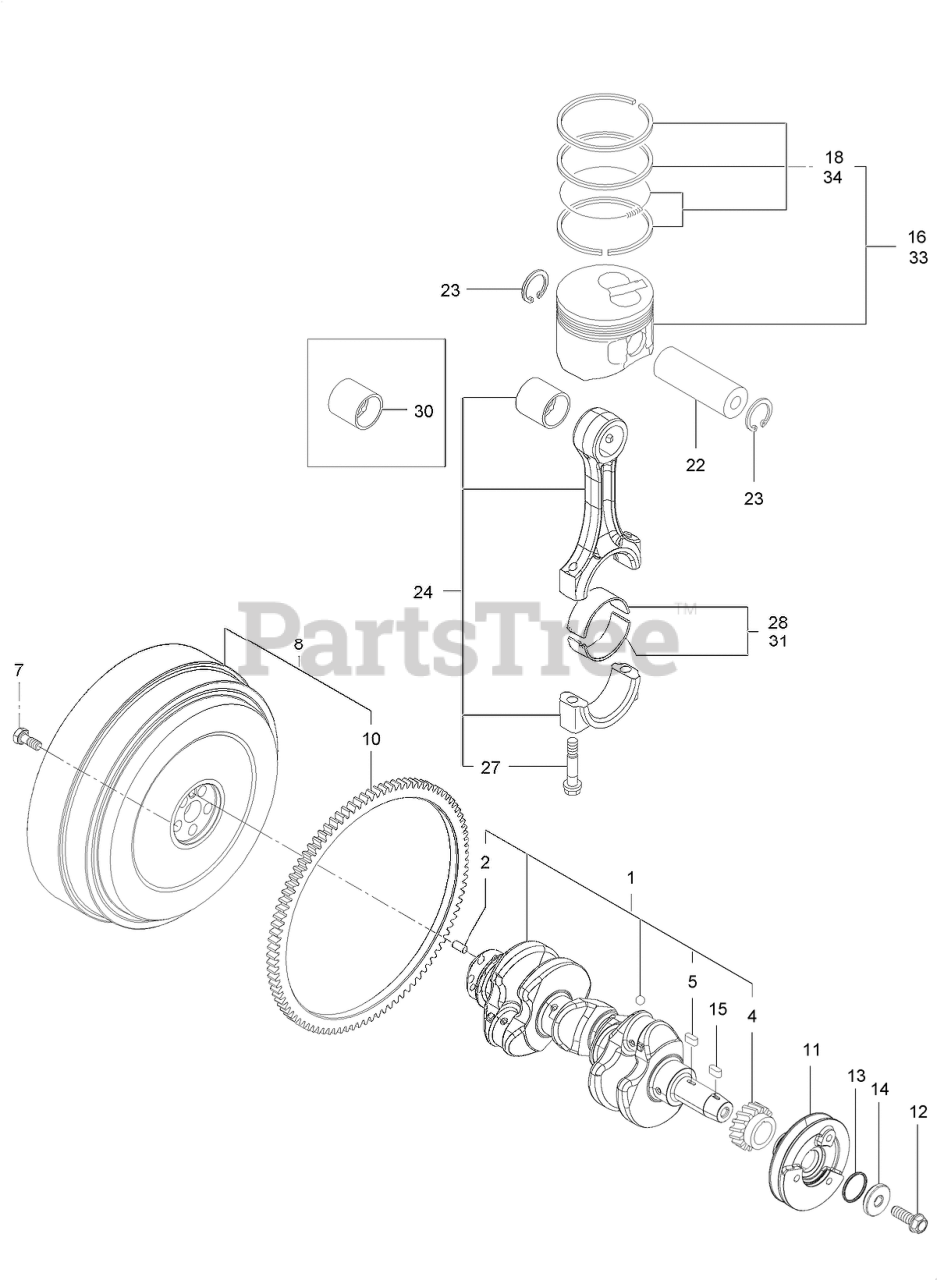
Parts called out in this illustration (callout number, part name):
1	CRANKSHAFT ASM
4	GEAR-CRANKSHAFT
7	BOLT, FLYWHEEL 5
8	FLYWHEEL ASM
10	GEAR-RING
11	V-PULLEY, CRANKSHAFT 1
12	BOLT, FLANGE 12X1.25 1
13	GASKET-WASHER
16	PISTON ASM
18	RING ASM
22	PIN-PISTON
24	ROD ASM-CONNECTING
27	BOLT-CONNECTING ROD
28	BEARING-CRANK PIN
30	BEARING-PISTON PIN
31	BEARING, PIN 0.25
33	PISTON ASM
34	RING ASM
